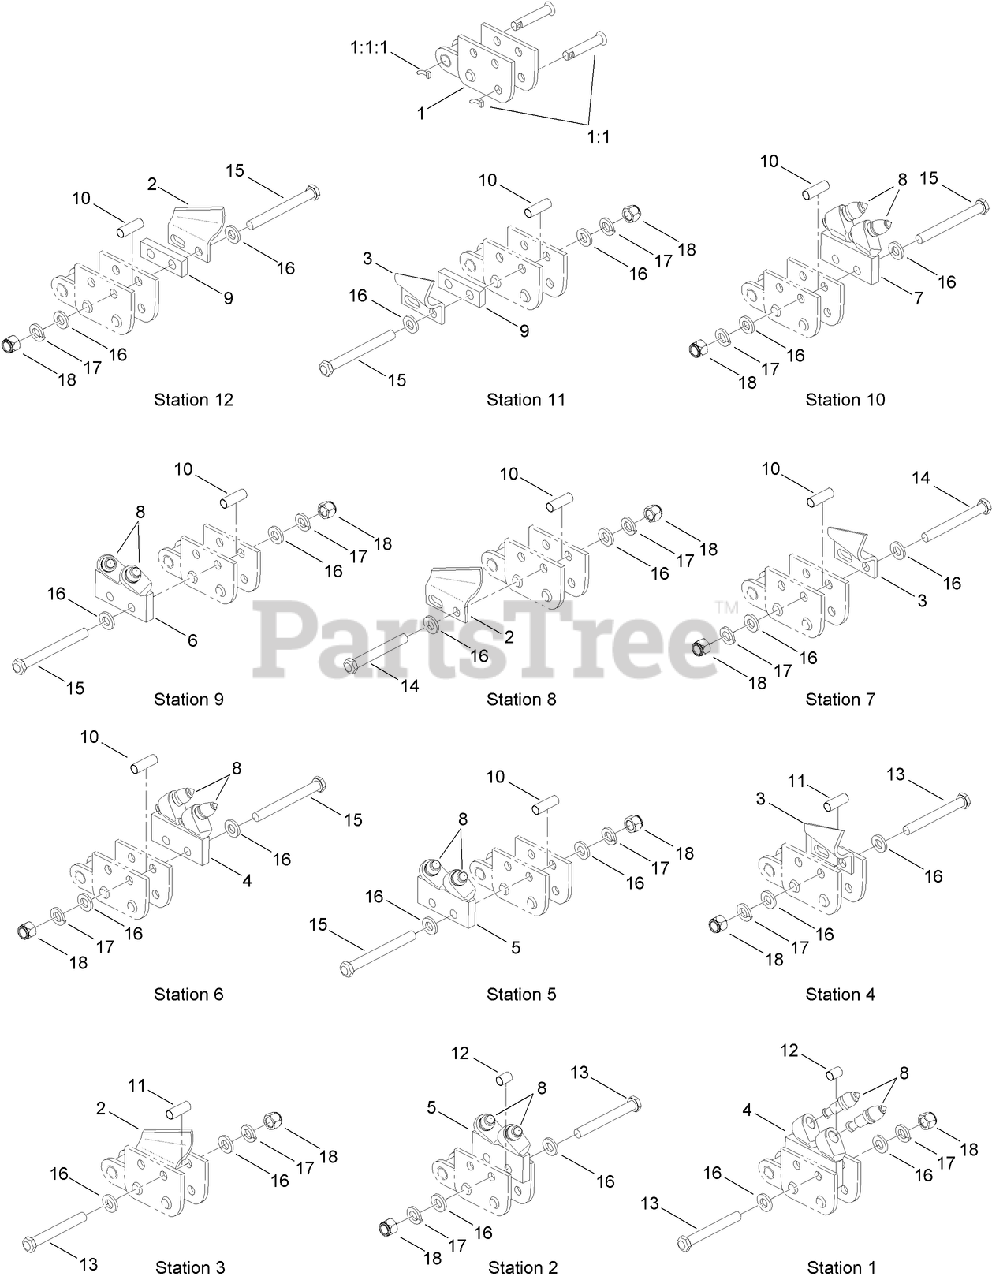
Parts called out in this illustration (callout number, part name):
1	CHAIN REPAIR LINK ASM
1:1	NOTCHED PIN AND KEEPER ASM
1:1:1	PIN-KEEPER
2	CUTTER-CUP, MIXED, LH
3	CUTTER-CUP, MIXED, RH
4	HOLDER-BIT, LH
5	HOLDER-BIT, RH
6	HOLDER-BIT, RH
7	HOLDER-BIT, LH
8	BIT-RETAINER, REAR
9	SPACER-FLAT
10	SPACER-TUBE, OUTSIDE MOUNT
11	SPACER-TUBE, INSIDE CUP MOUNT
12	SPACER-TUBE, INSIDE ADAPTER
13	BOLT-HH
14	BOLT-HH
15	BOLT-HH
16	WASHER-FLAT
17	WASHER-LOCK
18	NUT-LOCK
